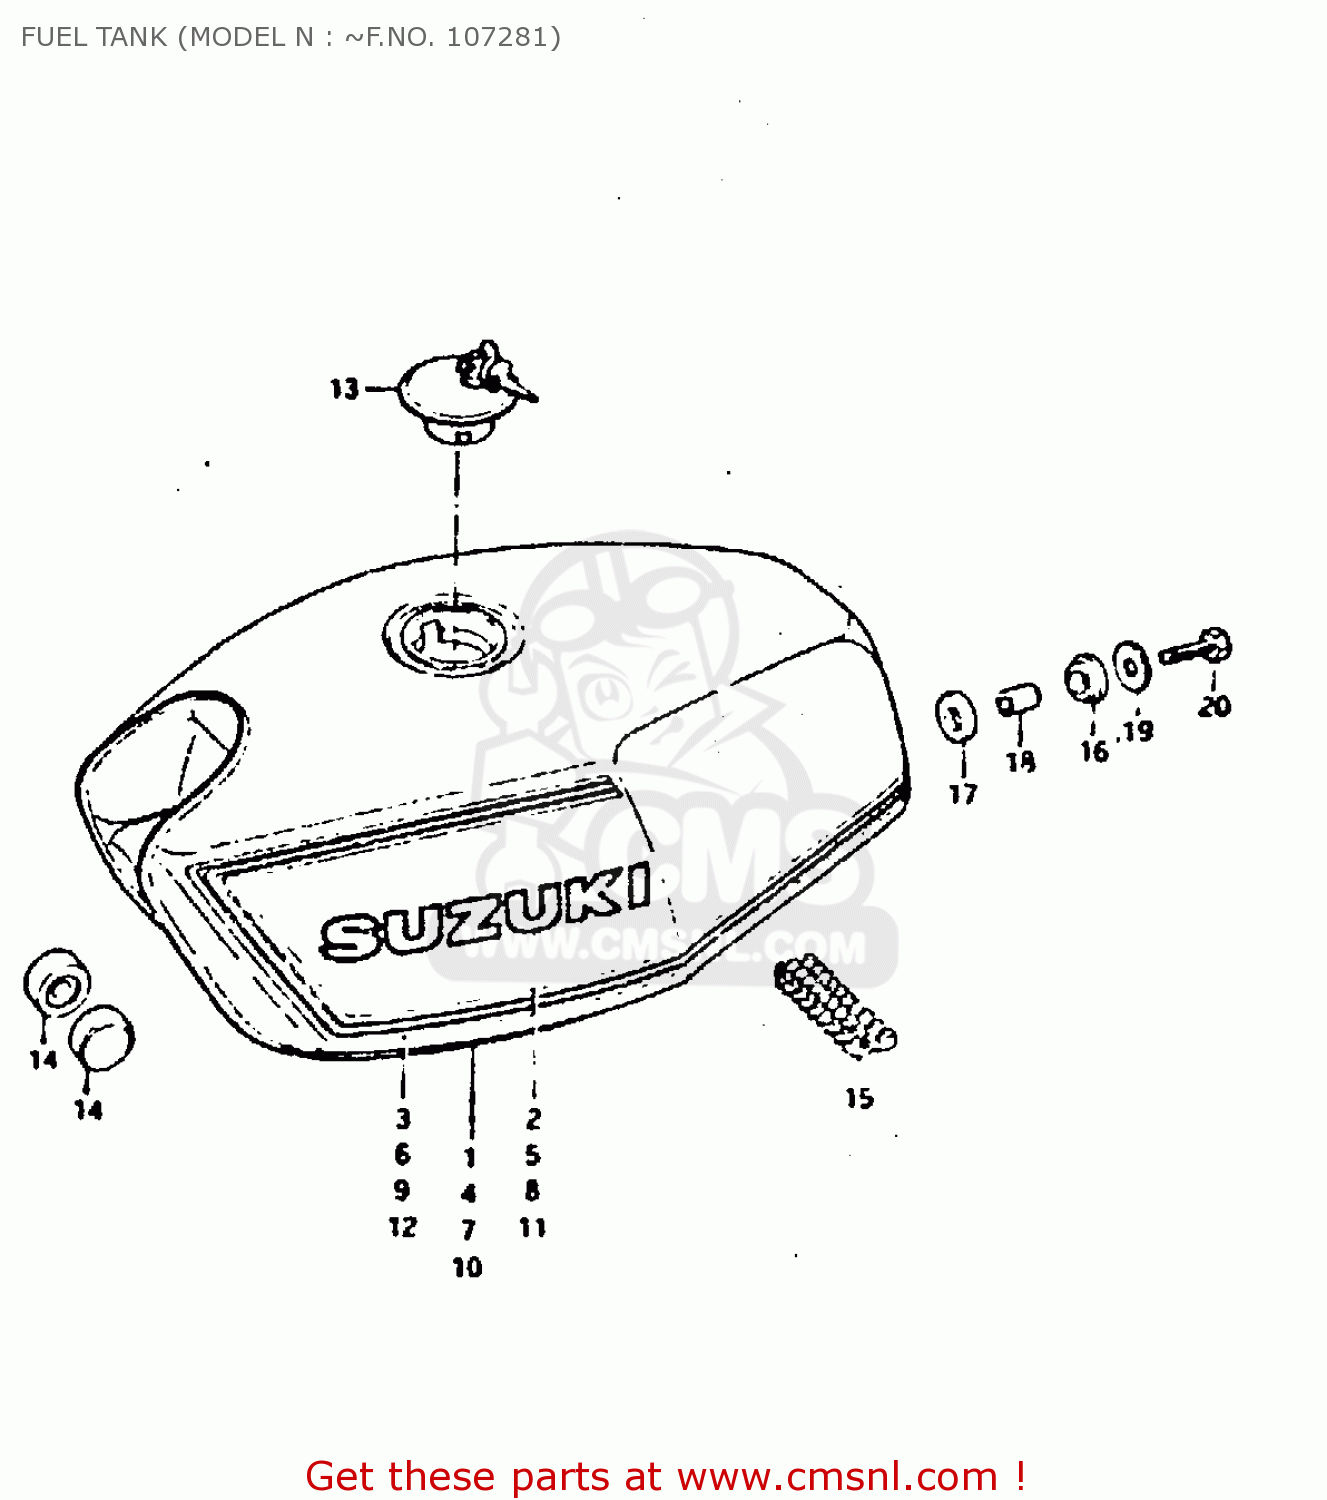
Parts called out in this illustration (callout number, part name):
1	TANK, FUEL (WHITE)
2	EMBLEM
3	TAPE SET (BLACK)
4	TANK, FUEL (RED)
5	EMBLEM
6	TAPE SET (BLACK)
7	TANK, FUEL (BLUE)
8	EMBLEM
9	TAPE SET (WHITE)
13	CAP SET,FUEL TANK
14	CUSHION
15	CUSHION
16	CUSHION
17	CUSHION
18	SPACER(8.5X12X19)
19	WASHER (8.5X29X1.6)
20	BOLT (8X30)
